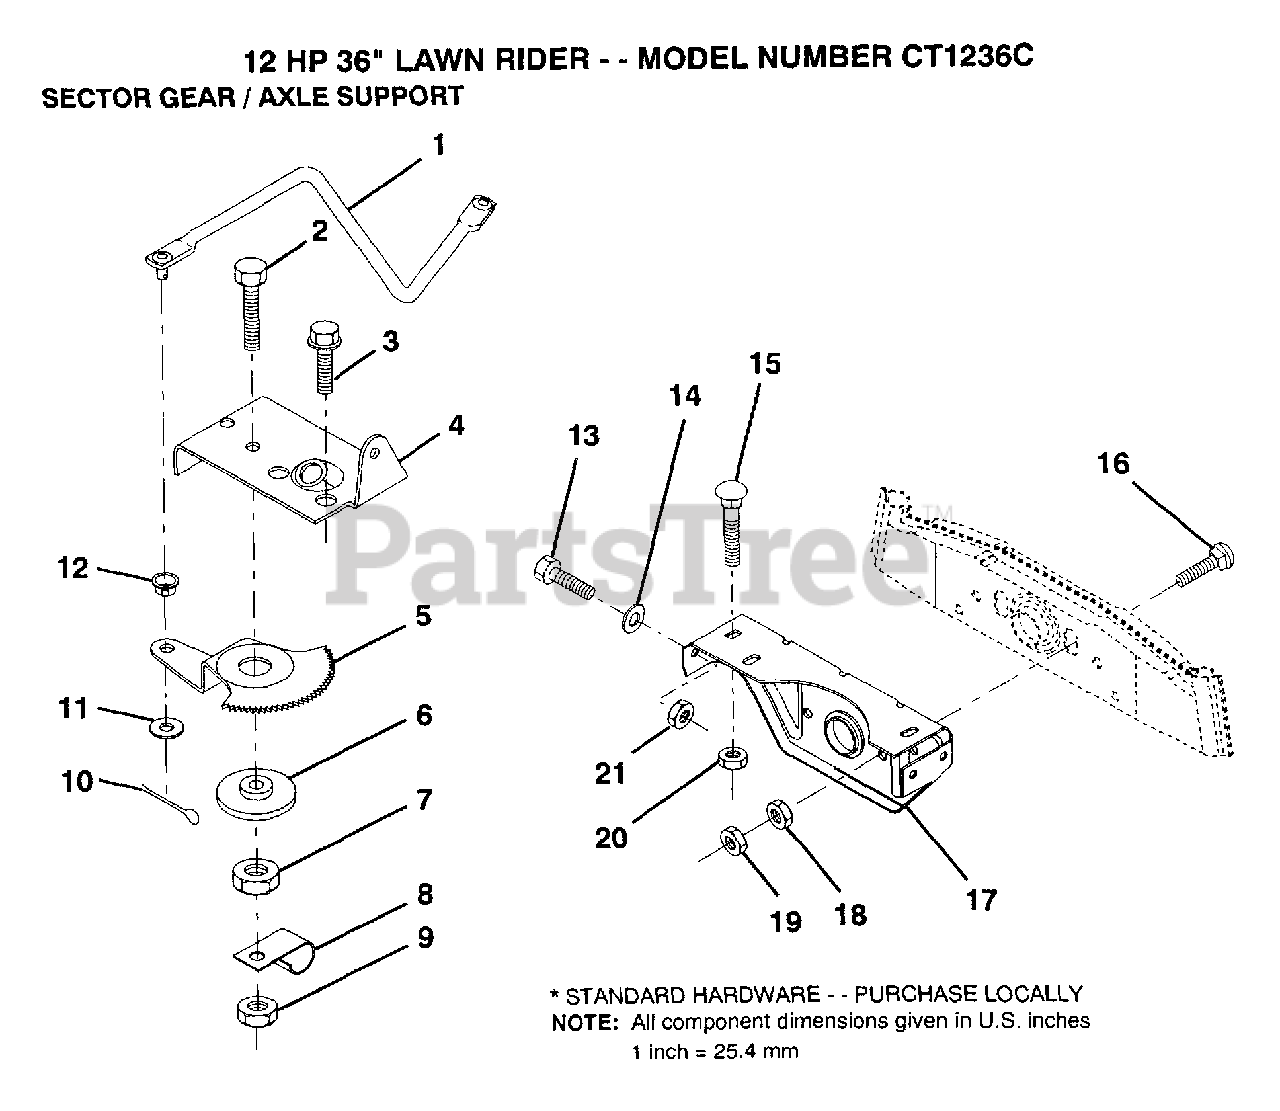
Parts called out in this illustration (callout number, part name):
2	"BOLT,HEX"
3	SCREW LT
4	"PLATE,STR SUPT"
5	GEAR SECTOR
6	BUSHING
7	NUT
8	CLIP INSULATOR
9	NUT LTV
10	COTTER PIN
11	WASHER
12	BUSHING.DRAGLINK
14	WASHER
15	BOLT
16	BOLT
17	"SUPT,FRT AXLE"
18	NUT.HEX.3/8-16UNC
19	LOCKNUT
